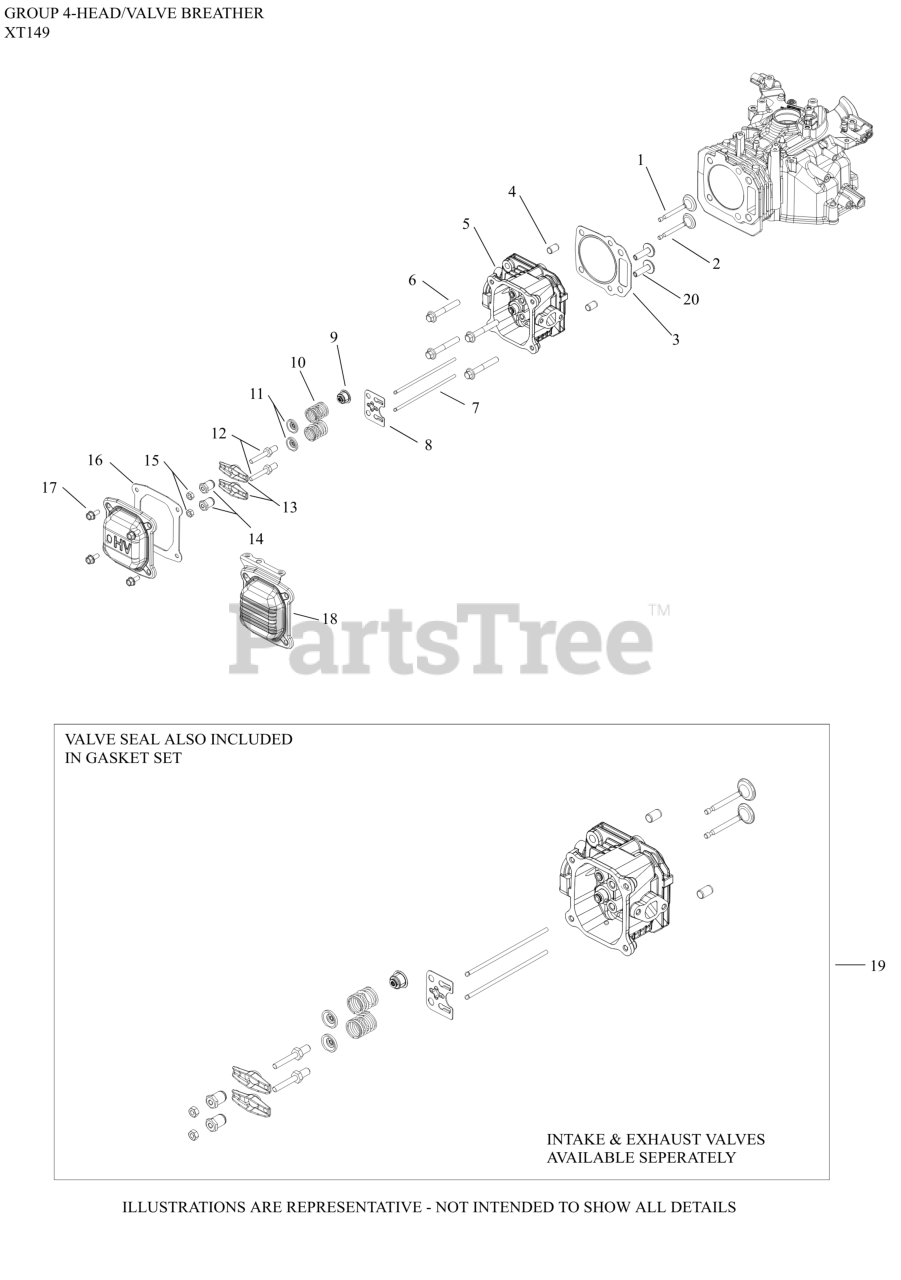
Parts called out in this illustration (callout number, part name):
1	VALVE INTAKE
2	VALVE, EXHAUST
4	DOWEL, CYLINDER HEAD-(#1438013S)
5	HEAD, CYLINDER - USE 14 318 07-S
6	SCREW, HEX FLANGE M8
7	ROD, PUSH
8	PLATE, PUSHROD GUIDE
9	SEAL, VALVE STEM
10	SPRING, VALVE
11	RETAINER, VALVE SPRING
12	STUD, ROCKER ARM-USE 14 072 22-S
13	ARM, ROCKER
14	PIVOT, ROCKER ARM
15	NUT, HEX JAM
16	GASKET, VALVE COVER
18	KIT, VALVE COVER - (#14 096 62-S)
19	KIT, VALVE TRAIN
20	LIFTER, VALVE
